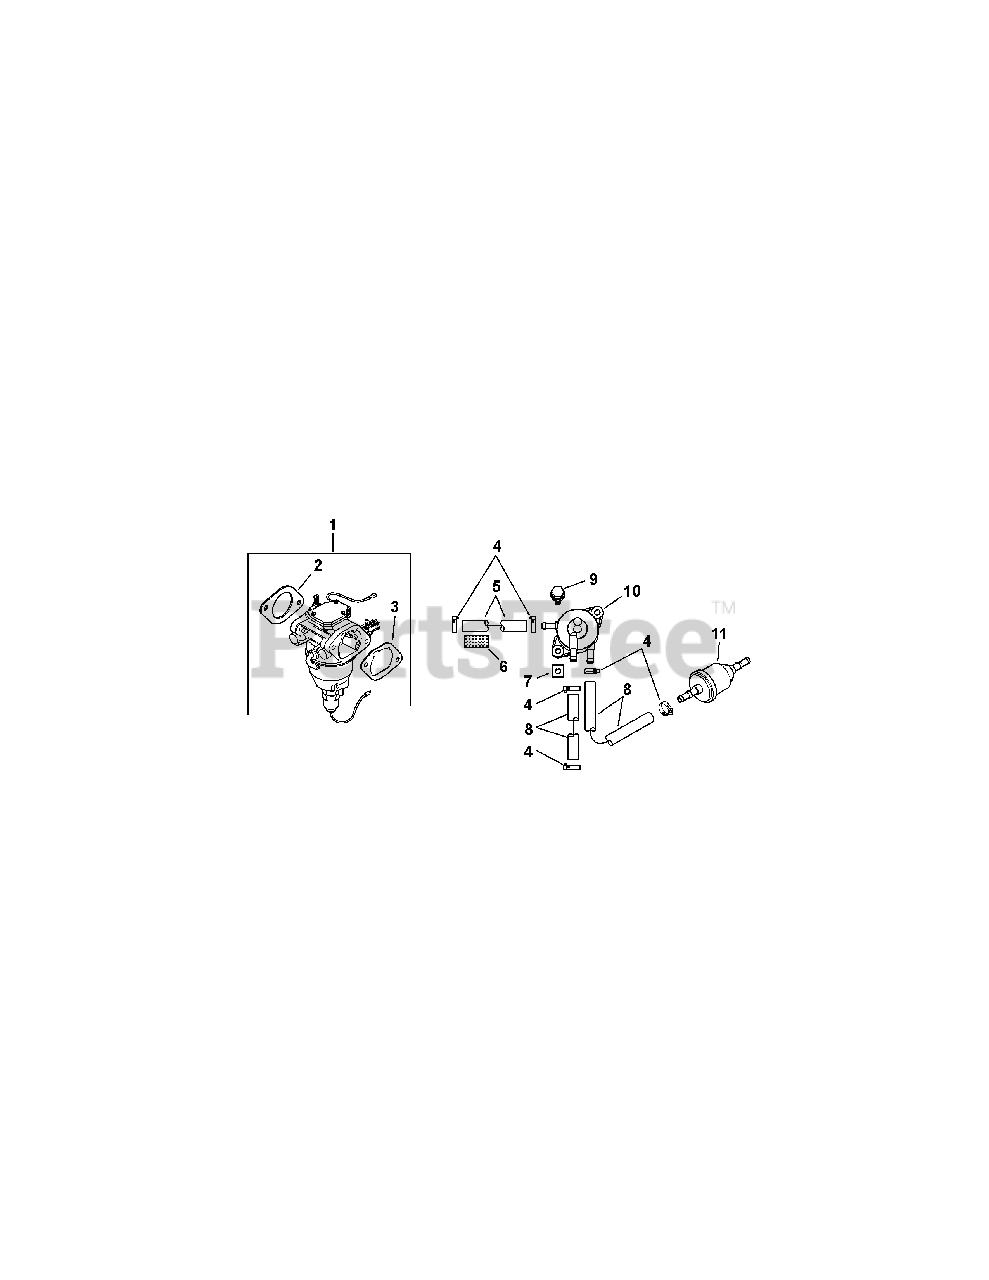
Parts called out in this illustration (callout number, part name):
1	KIT, CARBURETOR w/GASKETS (includes 2 & 3)
2	GASKET, CARBURETOR
3	GASKET, AIR CLEANER BASE
4	CLAMP, HOSE 1/2'
5	LINE, FUEL 11''
6	SLEEVE, INSULATING 14''
7	NUT, PLASTIC - BLACK
8	LINE, FUEL
9	SCREW, TAP M6X1.7X18
11	FILTER, FUEL
